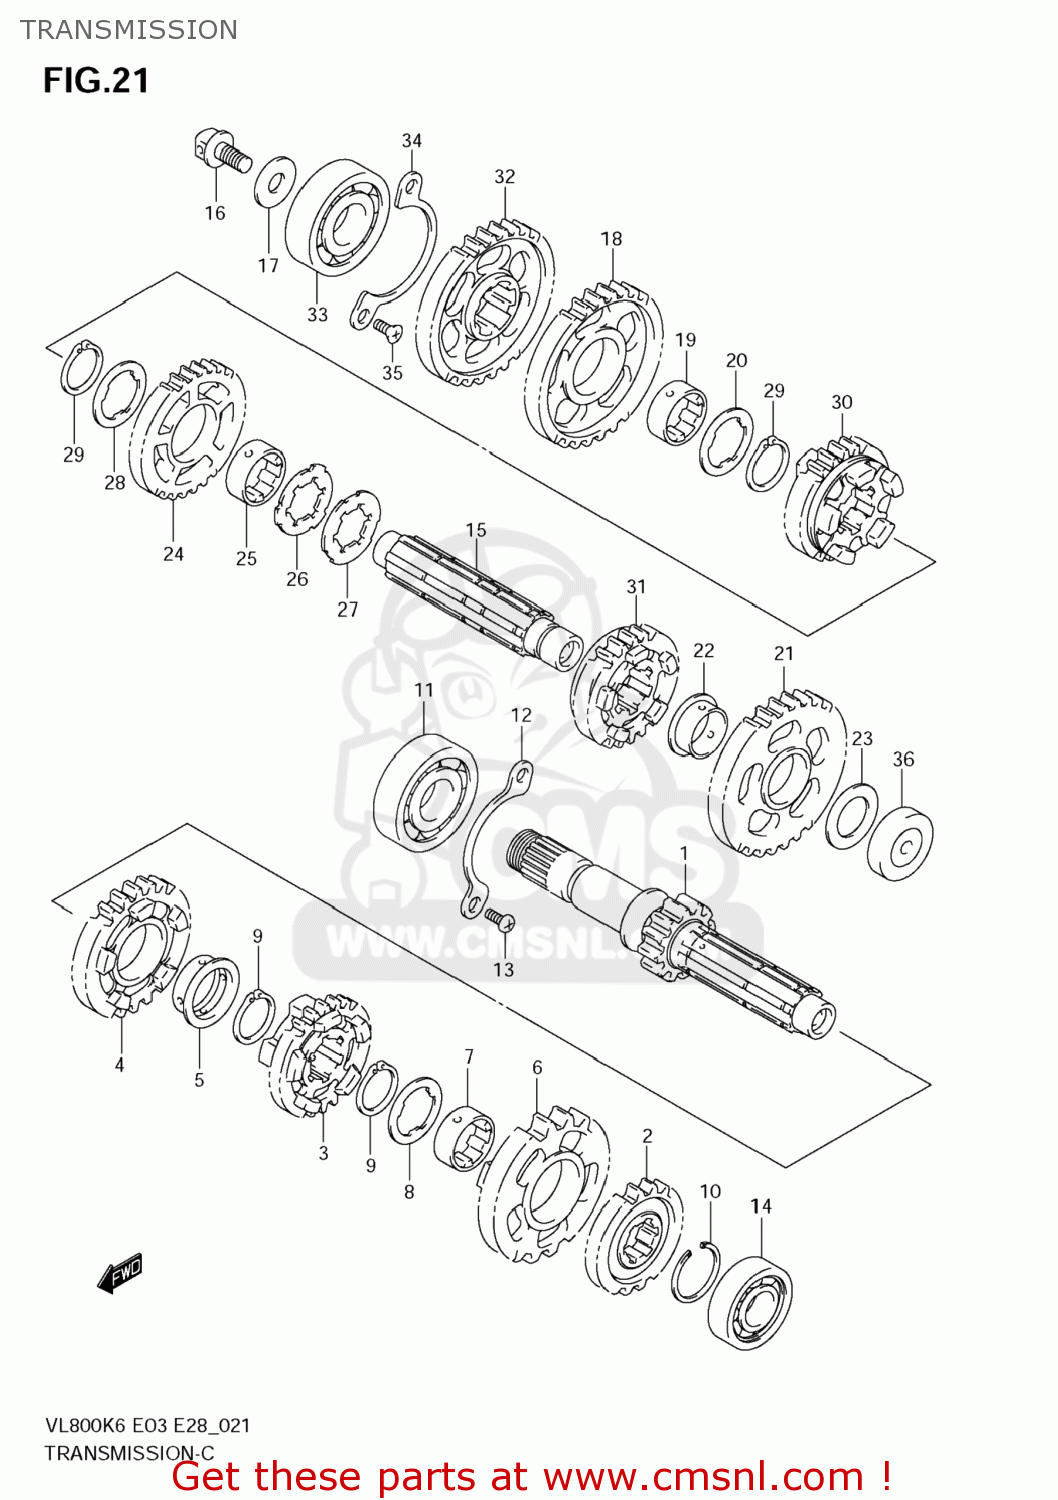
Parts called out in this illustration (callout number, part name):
1	SHAFT,COUNTER
2	GEAR,2ND DRIVE(NT:19)
3	GEAR,3RD DRIVE(NT:22)
4	GEAR,4TH DRIVE(NT:25)
5	BUSH
6	GEAR,5TH DRIVE(NT:27)
7	BUSH,6TH DRIVE GEAR
8	WASHER,LOCK
9	RING,SNAP
10	CIRCLIP
11	BEARING(25X62X17)
12	RETAINER,CNTR SHAFT BEARING
13	BOLT(6X12)
14	BEARING(20X47X14)
15	SHAFT,DRIVE
16	NOZZLE,DRIVE SHAFT
17	WASHER
18	GEAR,1ST DRIVEN(NT:32)
19	BUSH
20	WASHER,LOCK
21	GEAR,2ND DRIVEN(NT:31)
22	BUSH
23	SHIM(20X34X1)
24	GEAR,3RD DRIVEN(NT:27)
25	BUSH
26	WASHER
27	WASHER,LOCK
28	WASHER,LOCK
29	CIRCLIP
30	GEAR,4TH DRIVEN(NT:25)
31	GEAR,5TH DRIVEN(NT:22)
32	GEAR,REDUCTION DRIVE(NT:30)
33	BEARING(20X52X15)
34	RETAINER,DRIVE SHAFT BEARING
35	SCREW(6X12)
36	BEARING(20X52X15)
